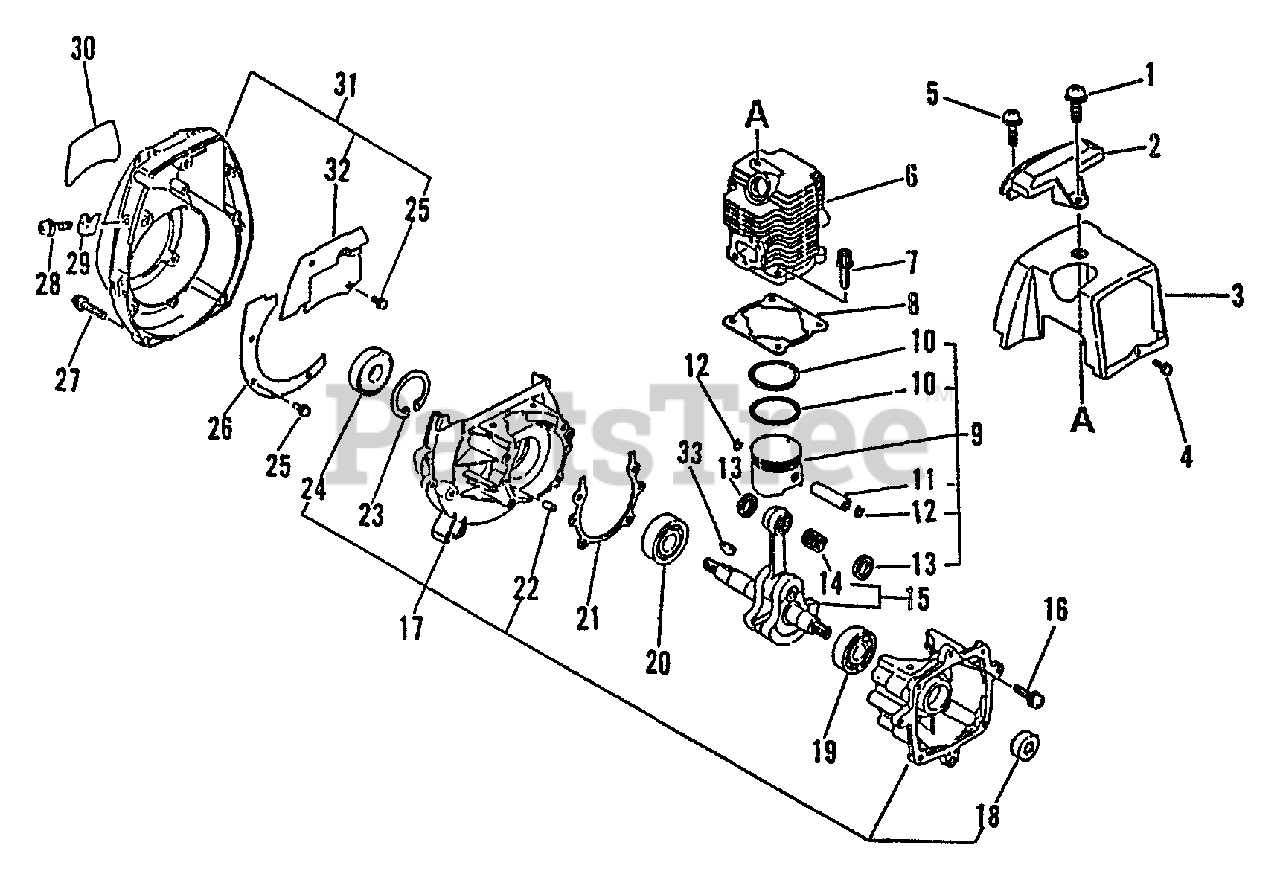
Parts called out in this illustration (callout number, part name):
1	SCREW - 5X16
2	GUARD - TOP
3	COVER, ENGINE
4	SCREW - 4X10
5	SCREW - 4X14
6	CYLINDER
7	SCREW - 5X20
8	GASKET, CYLINDER
9	PISTON KIT
10	RING, PISTON
11	PIN, PISTON
12	RING, RETAINING
13	SPACER, PISTON
14	BEARING, NEEDLE
15	CRANKSHAFT ASSY
16	SCREW - 5X25
17	CRANKCASE KIT
18	SEAL, OIL
19	BEARING, BALL - 6001C3
20	BEARING, BALL - 6201
21	GASKET, CRANKCASE
22	PIN - LOCATING
23	RING, RETAINING - 32
24	SEAL, OIL
25	SCREW - 4X8
26	SHIELD, FAN
27	SCREW - 4X20
28	SCREW - 4X10
29	HOLDER, CABLE
30	LABEL - MODEL LST-2400
31	FAN CASE ASSY
32	SHIELD, FAN
